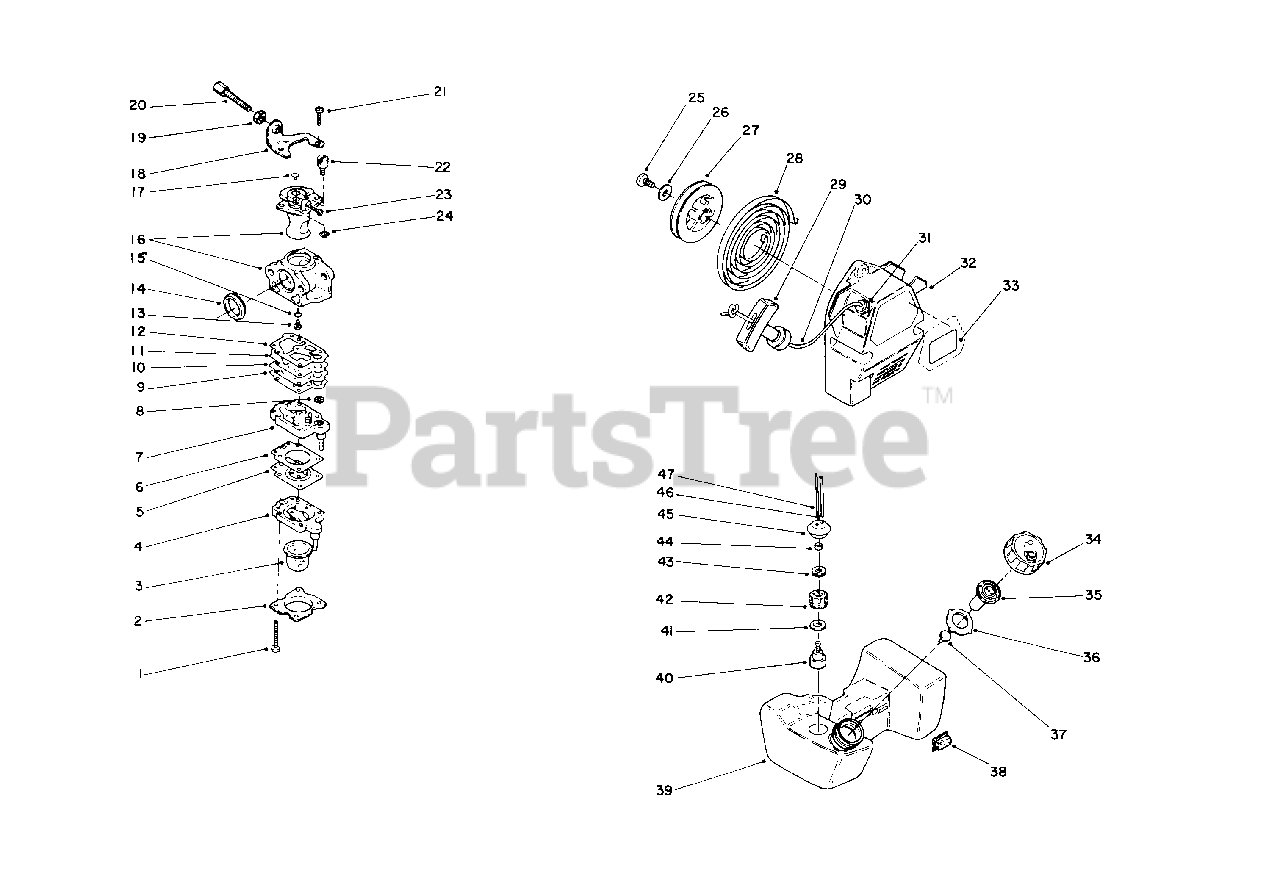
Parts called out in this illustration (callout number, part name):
2	Cover-Primer
3	Pump Assembly-Primer
4	Body-Primer
5	Diaphragm
6	Gasket-Diaphragm
7	Body-Pump
9	Gasket-Pump
11	Diaphragm
12	Gasket-Diaphragm
13	Jet-Main #43
14	Gasket-Rubber
15	O-Ring, Main Jet
16	Body-Carburator (Ref.)
19	Nut-Lock
20	Screw-Adjustment
22	Pivot-Cable
23	Valve-Throttle
29	Knob-Starter
30	Rope-Starter
32	Case-Starter
33	Decal-Toro
34	Cap-Fuel
35	Valve-Breather
37	Cap-Valve
39	Tank Assembly-Fuel
40	Weiqht-Filter
42	Filter-Fuel
43	Washer-Seal
45	Grommet-Fuel Tank
46	Hose-Fuel
47	Tube-Fuel Return
